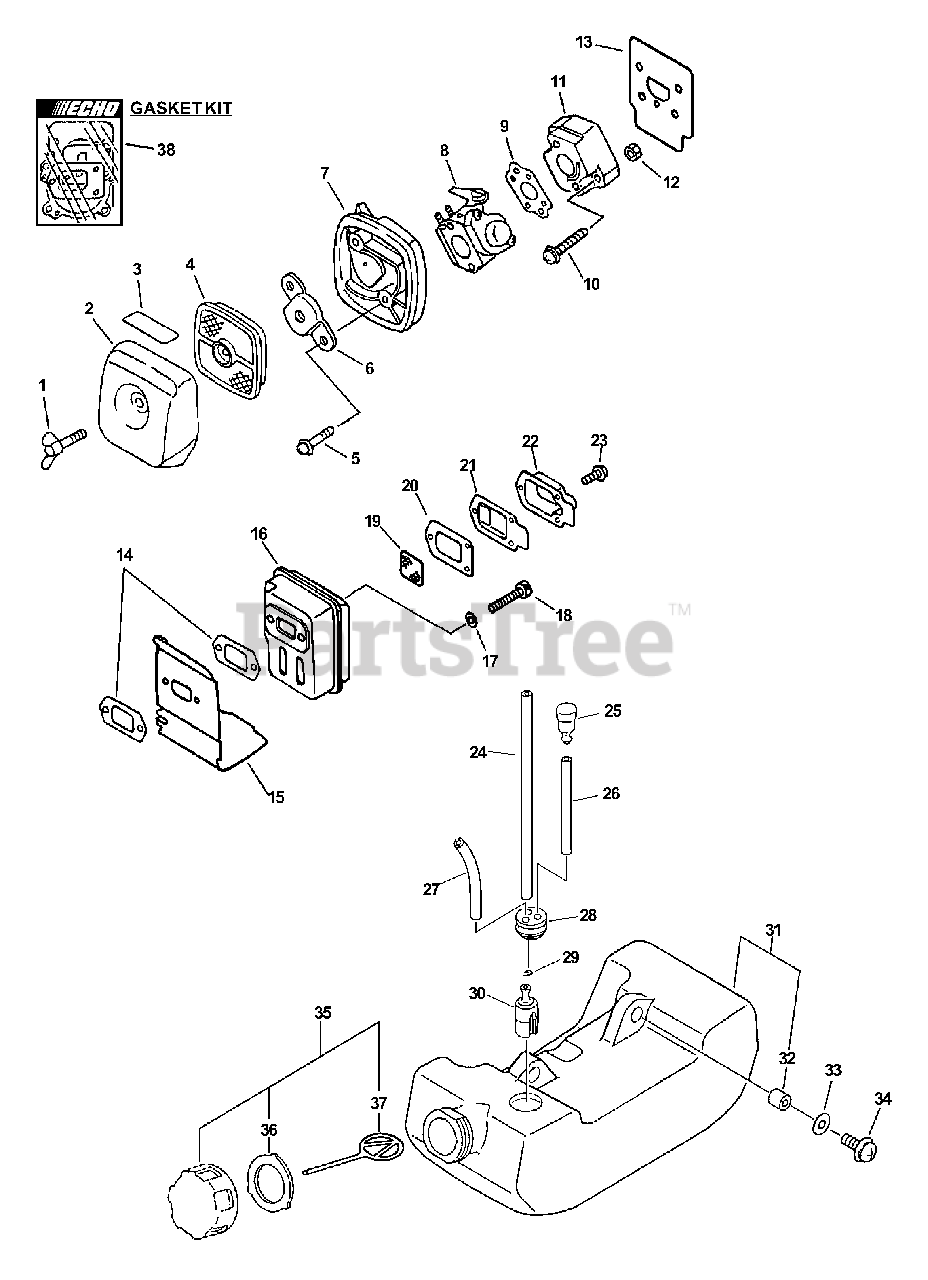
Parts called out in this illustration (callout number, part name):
1	THUMBSCREW
2	COVER, AIR FILTER - GRAY
3	LABEL - CHOKE
4	FILTER, AIR - SINGLE LAYER
5	SCREW - 5X65
6	PLATE, PREVENT
7	AIR FILTER CASE KIT - GRAY
8	CARBURETOR C1U-K52
9	GASKET, INTAKE
10	SCREW - 5X20
11	INSULATOR, INTAKE
13	SHIELD, INTAKE
14	GASKET, EXHAUST
15	SHIELD, EXHAUST
17	WASHER - 5
18	SCREW - 5X55
19	SCREEN, SPARK ARRESTOR
20	GASKET, EXHAUST
21	GUIDE, EXHAUST - OUTER
22	GASKET, EXHAUST - INNER
23	SCREW - 4X10
24	PIPE - 3X5X180 -- BLACK
25	VENT, FUEL TANK
26	PIPE - 3X5X70 -- BLACK
27	PIPE - 3X6X90 -- CLEAR
28	GROMMET
29	CLIP - 6
30	FILTER, FUEL
31	FUEL TANK ASSY
33	WASHER - 5
34	SCREW - 5X16
35	CAP ASSY - ORANGE
36	GASKET, CAP
37	CONNECTOR, CAP
38	GASKET KIT
